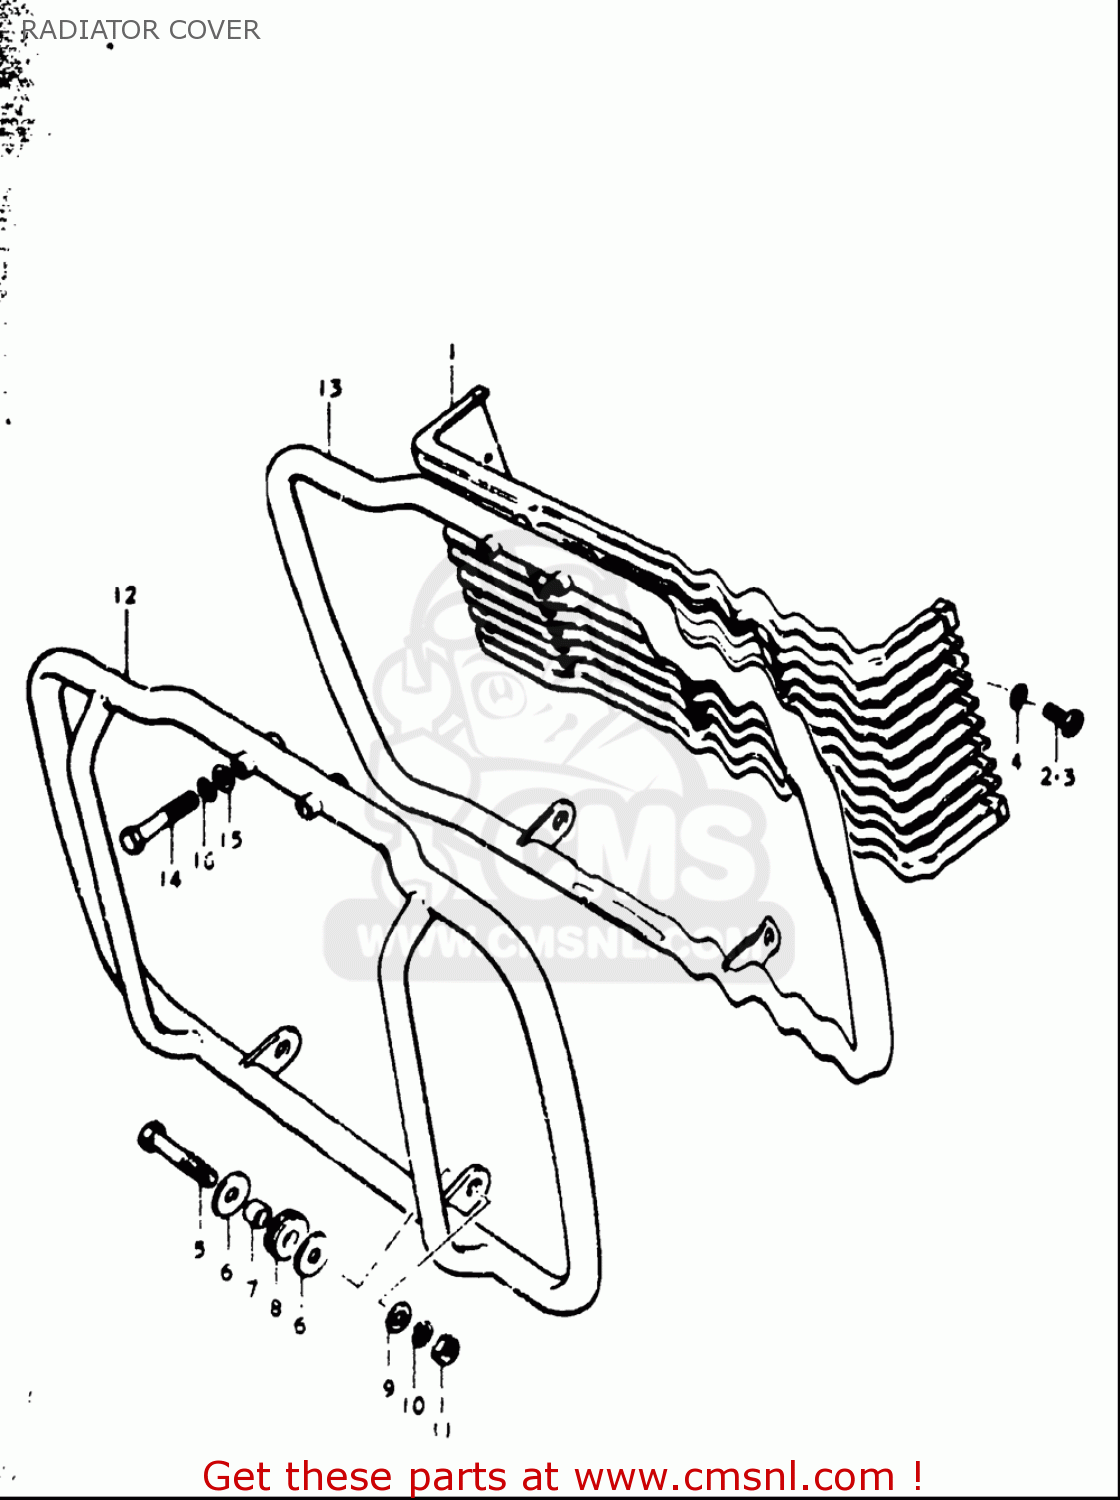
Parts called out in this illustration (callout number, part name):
2	SCREW
4	O RING(D:3.5,ID:5.8)
5	BOLT
6	WASHER(8.5X28X1.6)
7	SPACER,8.5X14X9
8	CUSHION
9	WASHER
10	WASHER,LOCK
11	NUT
14	BOLT
15	WASHER
16	WASHER,LOCK
